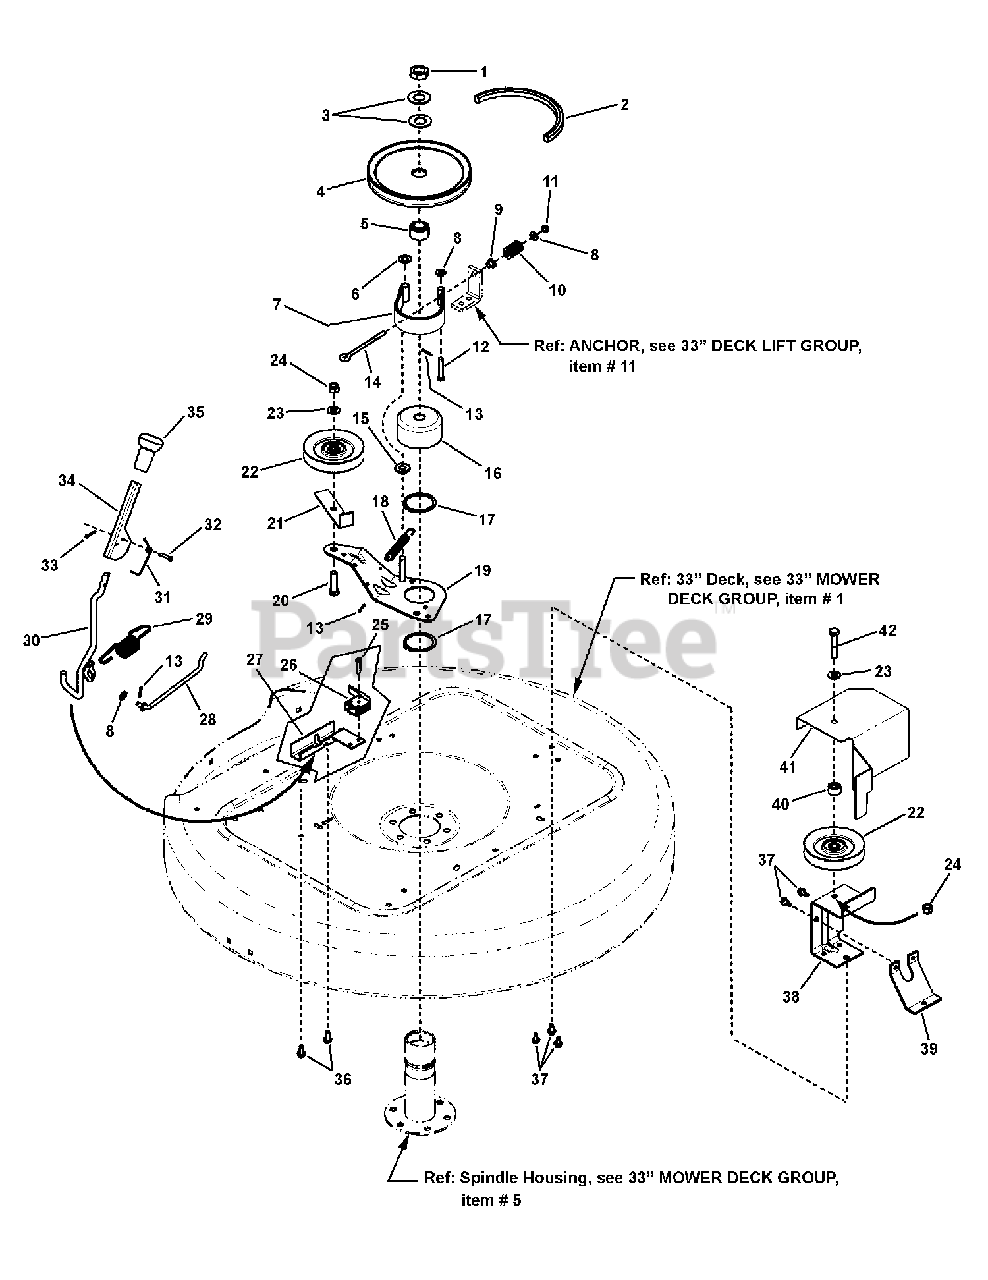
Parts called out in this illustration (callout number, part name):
1	NUT, 3/4-16 Hex Jam, GR 8
2	* BELT, Drive (73.75" AA Section)
3	WASHER, 49/64" I.D. x 1-1/2" O.D. Flat
4	PULLEY, Deck
5	PULLEY, Hub (Powdered Metal)
6	WASHER, 3/8" Flat SAE
7	BAND, Brake (Formed)
8	WASHER, .28 x .63 x .06 Flat, GR 5
9	BUSHING, Flange .27 x .35 x .4
10	SPRING, Rectangular Wire Die, Blue
11	NUT, 1/4-20 Hex Top Lock
12	PIN, 1/4 x 1-5/8" Clevis
13	PIN, 3/32 x 3/4" Cotter
14	EYE-BOLT, 1/4-20 x 4"
15	SPACER, .39 x 1.0 x .31 Nylon
16	DRUM, Brake Spindle (3" OD, 1.6" Tall)
17	RING, 2" External Retaining
18	SPRING, Extension, 4" x 1/2" Diameter
19	WELDMENT, Idler Arm
20	SCREW, 3/8-16 x 1-1/2" Hex Head Cap, GR 5
21	RESTRICTOR, Belt
22	PULLEY, Idler (3/8" ID, 4" OD)
23	WASHER, 3/8" Flat
24	NUT, 3/8-16 Hex Nyloc
25	SCREW, #10-32 x 1" Hex Washer Head Self-Tap
26	SWITCH, Deck Interlock (NO)
27	MOUNT, Handle/Switch
28	ROD, Idler Control
29	SPRING, Blade Handle
30	WELDMENT, Blade Engagement Handle
31	SPRING, Torsion, Flip Handle
32	PIN, 3/16 x 1" Clevis
33	PIN, 3/32 x 1/2" Cotter
34	HANDLE, Blade Engagement (Flip)
35	GRIP, Handle
36	SCREW, 1/4-20 x 5/8" Hex Washer Head Self-Tap
37	SCREW, 5/16-18 x 1/2" Hex Washer Self-Tap
38	BRACKET, Fixed Idler
39	BRACE, Fixed Idler Bracket
40	SPACER, Idler
41	GUARD, Pulley
42	SCREW, 3/8-16 x 2" Hex Head Cap, GR 5
